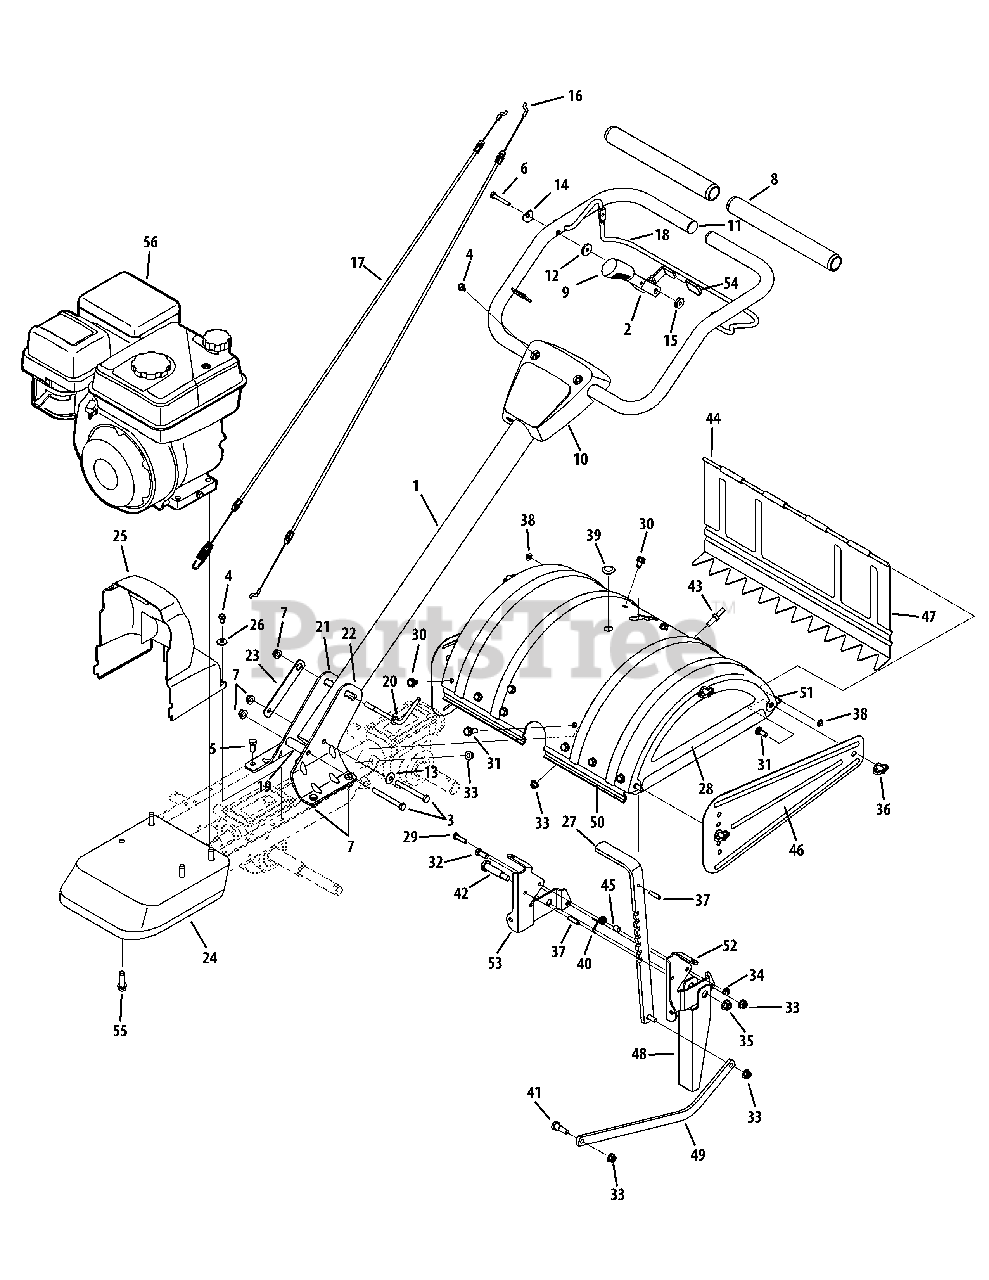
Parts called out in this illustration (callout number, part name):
1	Upper Handle Assembly
2	Reverse Handle Assembly
3	Hex Screw, 5/16-18 x 3.00
4	Hex Washer Screw, 1/4-20 x 0.500
5	Hex Washer Screw, 5/16-18 x .875
6	Hex Lock Screw, 1/4-20 x 1.62
7	Flange Lock Nut, 5/16-18
8	Foam Grip, .970 x 11.0
9	Selector Handle Grip
10	Handle Cover, 400
11	End Plug
12	Flat Washer, .265 x .938 x .120
13	Bell Washer, .340 x .872 x .060
14	Saddle Washer, .320 x .93 x .060
15	Shoulder Spacer, .375 x .165
16	Reverse Cable
17	Forward Cable
18	Bail
19	Spacer, .322 x .625 x 2.00
20	Handle Adjustment Crank
21	RH Handle Bracket
22	LH Handle Bracket
23	Retainer Bracket
24	Front Bumper
25	Belt Cover
26	Flat Washer, .28 x .74 x .063
27	Depth Adjustment Bracket
28	End Cover Assembly
29	Hex Screw, 1/4-20 x 1.00
30	Hex Washer Screw, 5/16-18 x 0.625
31	Hex Washer Screw, 5/16-18 x .875
32	Hex Screw, 5/16-18 x .75
33	Flange Lock Nut, 5/16-18
34	Flange Lock Nut, 1/4-20
35	Flange Lock Nut, 3/8-16
36	Wing Nut w/ Bell Washer, 5/16-18
37	Spring Pin, 1/4 x 1.00
38	Cap Speed Nut, 1/4
39	Deck Hole Plug
40	Torsion Spring
41	Shoulder Screw, 5/16-18 x .405 x .345
42	Shoulder Screw, .498 x 1.635
43	Hex Screw, 5/16-18 x .75
44	Tiller Flap Rod
45	Round Spacer, .370 x .260 x .410
46	Side Shield
47	Rear Tine Shield
48	Stop Reverse Arm
49	Depth Drag Bar
50	Tine Shield Mount Bracket
51	Tine Shield
52	LH Tail Bracket
53	RH Tail Bracket
54	Reverse Handle Grip
55	Replacement Engine
